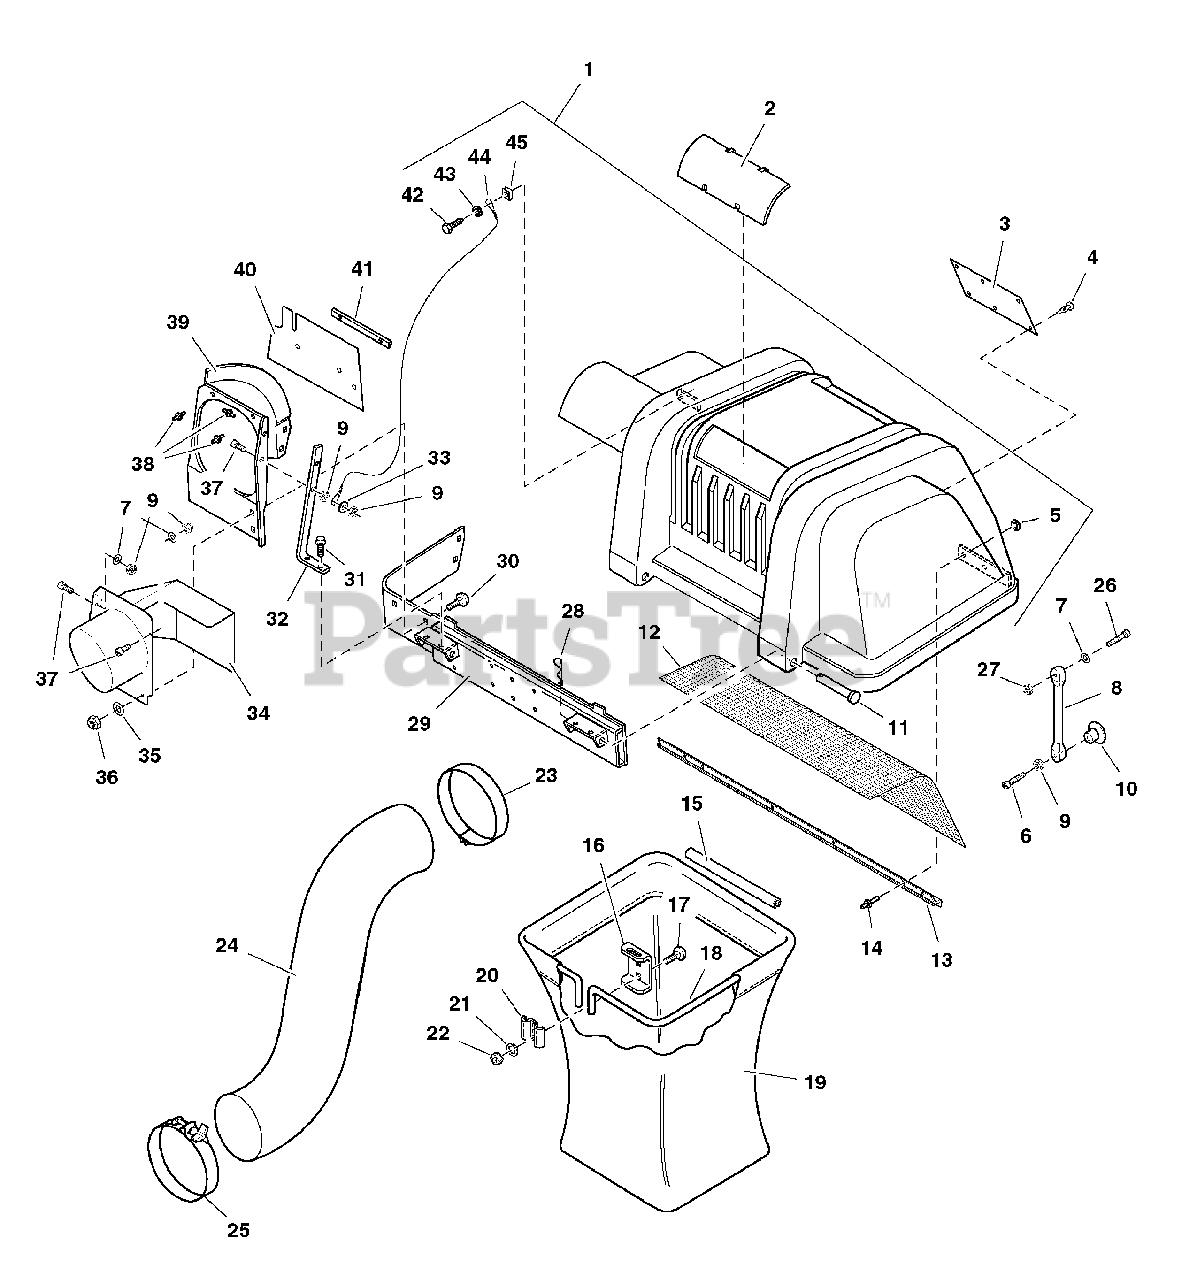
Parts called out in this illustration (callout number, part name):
1	COVER & SCREEN ASSEMBLY
2	WINDOW
3	DECAL, Safety
4	CLIP, Canoe
6	SCREW, #10-32 x 1-1/2
7	WASHER, 3/16" USS
8	RUBBER STRAP
9	NUT, #10-32 Hex Nylon Lock
10	KNOB
11	PIN, Round Head
12	SCREEN
13	SEAL, Clip
14	RIVET, Pop
15	TUBE CLIP, Grass Bag
16	HANGER
17	CARRIAGE BOLT,5/16-18 x 3/4
18	HOOP, Bag
19	BAG, Grass (Black)
20	CLAMP
21	WASHER, 5/16" Lock
22	NUT, 5/16-18 HEX
23	HOSE CLAMP, Upper
24	HOSE, FLEXIBLE, 7" DIA. X 58"
25	HOSE CLAMP, Lower
26	SCREW, #10-24 X 1 RS, CZ
27	NUT, #10-24 Hex Nylon Lock
28	CLIP, Hairpin
29	CROSS ASSEMBLY
30	BOLT,1/4-20X0.750,GR5,STD NECK,SQ,ZC/CL
31	SCREW, Taptite, 1/4-20 x 3/8
32	STRAP, Tube Support
33	WASHER, Fender, 3/16
34	HOSE ADAPTER / DEFLECTOR
35	WASHER, 1/4 SAE
36	NUT, 1/4-20 Hex Nylon Lock
37	SCREW, #10-32 x 3/4
38	RIVET, Pop
39	SUPPORT, Tube
41	BRACKET, Seal
42	SCREW, Self-tapping, #10-12 x 5/8
43	WASHER, 1/4
44	CABLE, Double Loop
45	NUT, Speed
